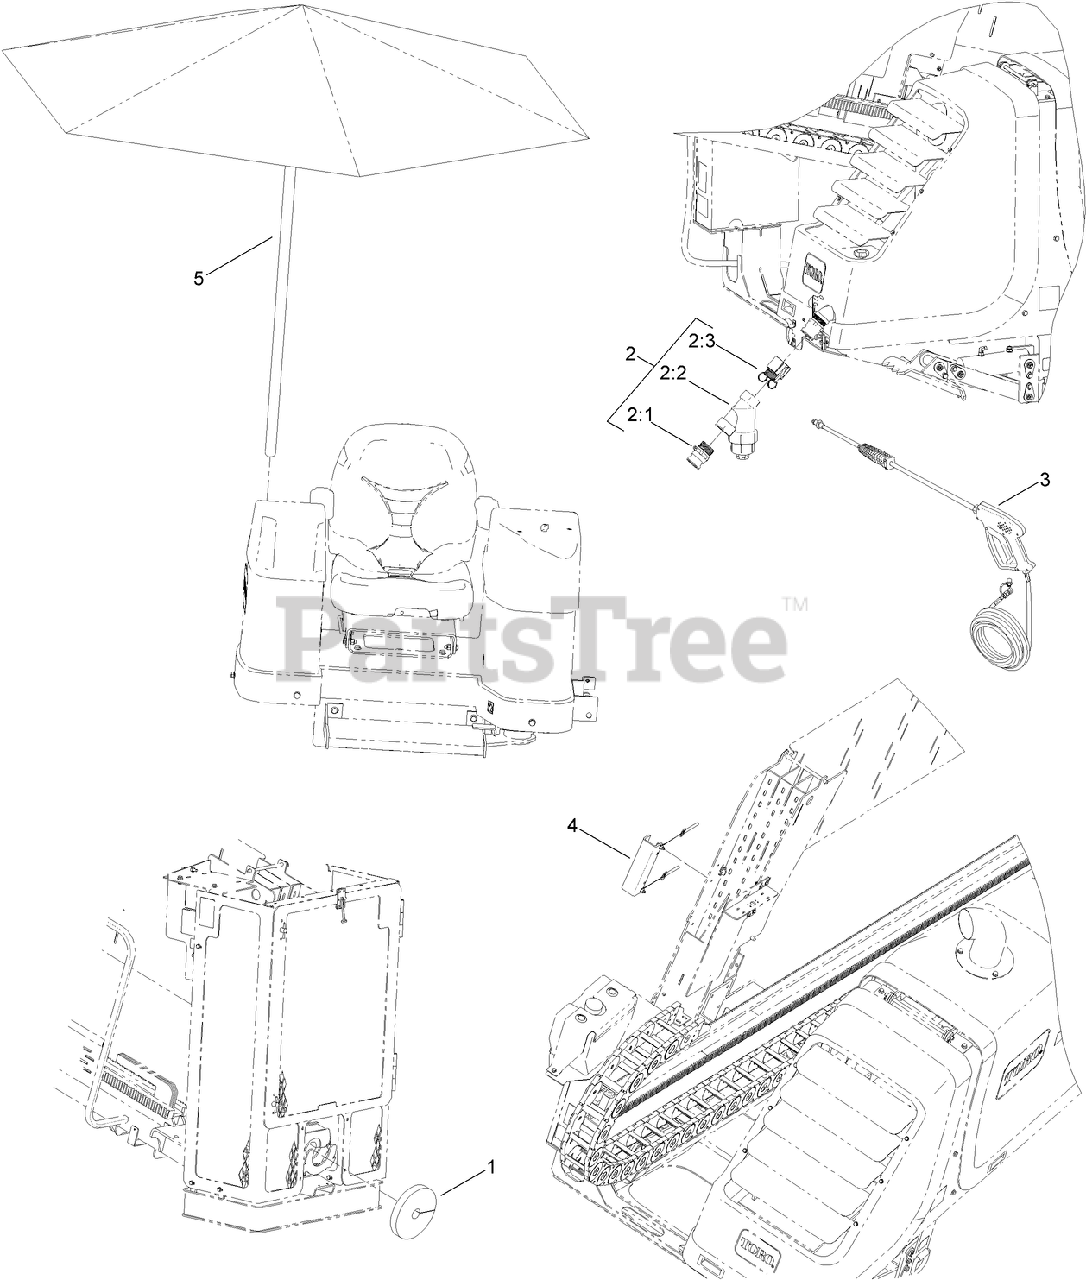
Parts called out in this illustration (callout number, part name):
1	WIPER-PIPE
2	STRAINER KIT
2:1	ADAPTER-MALE
2:2	STRAINER-Y
2:3	FITTING-CAMLOK
3	WASH DOWN WAND ASM
4	CYLINDER LOCKOUT ASM
5	UMBRELLA-TORO
